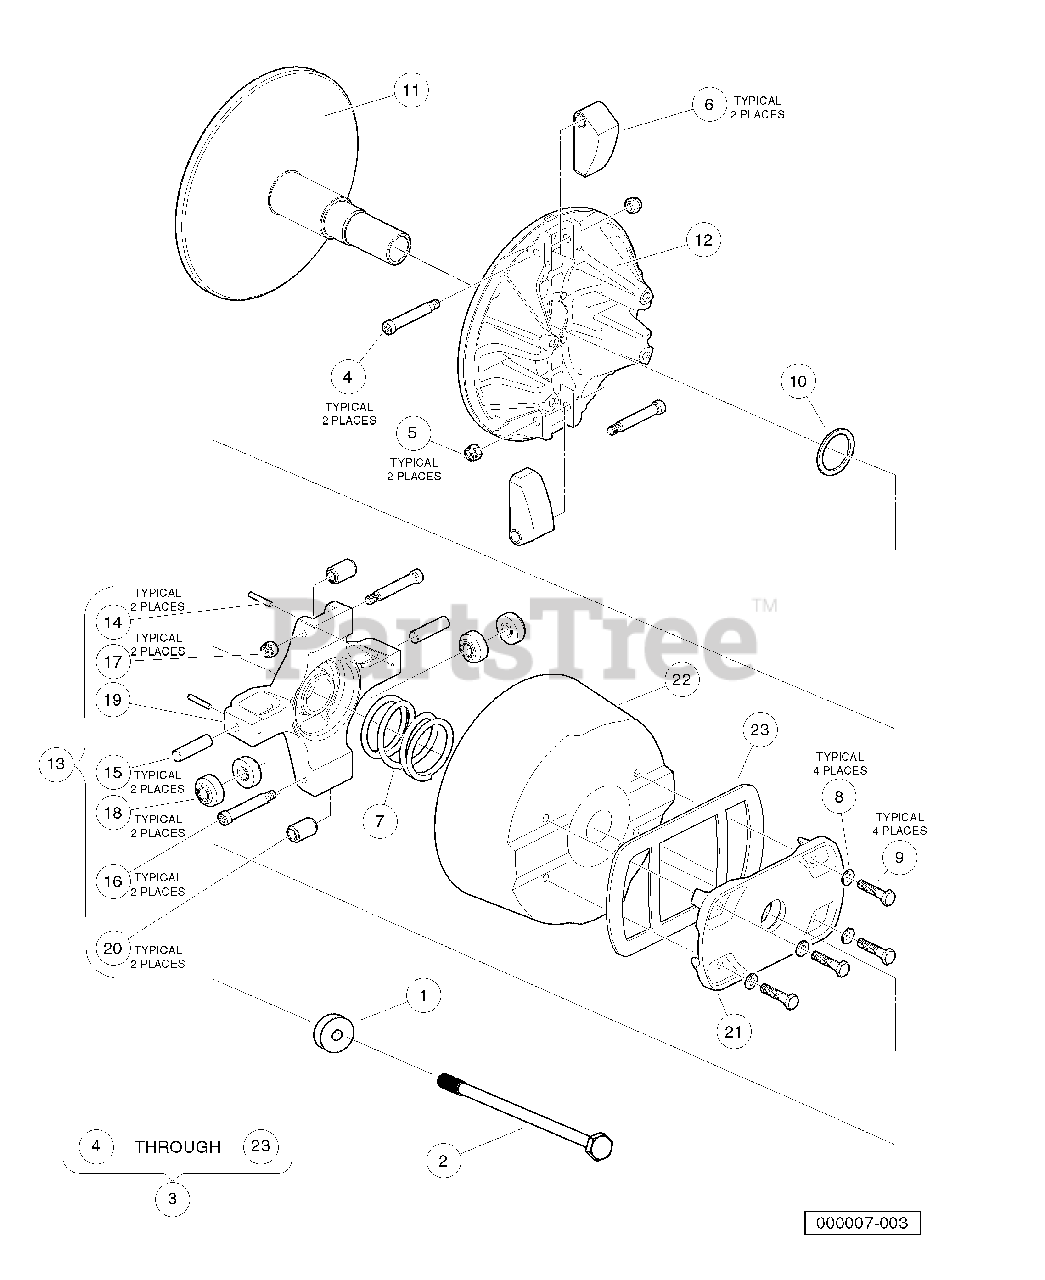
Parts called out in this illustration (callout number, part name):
1	Washer, Stepped
2	Bolt, M10x1.25x200 Loctite
3	Clutch, 4x4, Gas, W/cover
4	Screw, Shlder Hex, .312 X 1.75
5	Nut, Lock Hex, 1/14-20, Flexlc
6	Sub Assy, Wt Clutch, Gas
7	Spring, Compression, Primary
8	Washer, Lock, H-Spring, 1/4
9	Screw, Cap, Hex Hd, 1/4 X 1.25
10	Shim, 1.63 X 1.33
11	Subassembly, Drive Clutch
12	Subassembly, Moveable, Drive Clutch
13	Spider Subassembly
14	Pin, Spring Slotted,1.25 X 1.0
15	Pin, Dowel, .375 X 1.50
16	Screw, Shlder Hex, .312 X 1.75
17	Nut, Lock Hex, 1/14-20, Flexlc
18	Roller, Torque, Gas
19	Spider, Drive Clutch
20	Sub Assy, Roller Weight
21	Cover, Drive Clutch
22	Cover, Clutch, 4x4
23	Gasket, Cover, Clutch, 4x4
